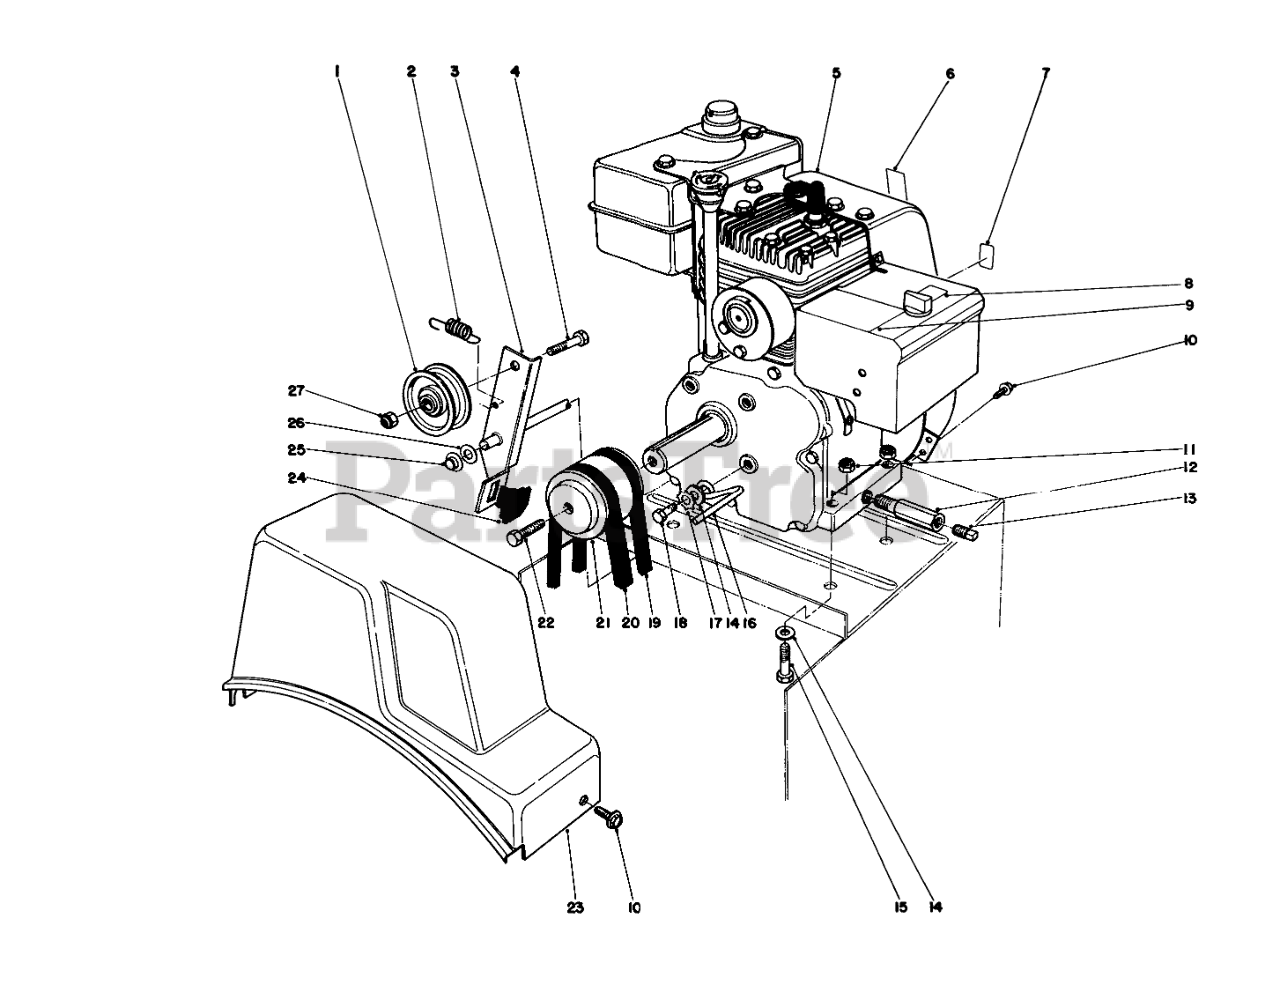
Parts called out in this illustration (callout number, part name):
1	PULLEY-IDLER
2	EXTENSION SPRING
3	Auger Clutch Rod Assembly (Incl. Ref. #24)
4	SCREW-HH
5	Engine
6	PRIMER DECAL
7	DECAL THROTTLE
8	CHOKE DECAL
9	Decal Hot Surface Warning
10	SCREW
11	NUT-LOCK, NI
12	PIPE-NIPPLE
13	CAP-PIPE
14	WASHER-PLAIN
15	SCREW-HH
16	RETAINER-BELT
17	WASHER-LOCK
18	SCREW-HH
19	V BELT-3L, TRACTION
20	V-BELT (29.50 INCH)
21	PULLEY-ENGINE
22	SCREW-SPECIAL
23	COVER-BELT
24	Brake Pad
25	RETAINER-PUSH ON
26	WASHER-FLAT
27	NUT-LOCK, CONE
